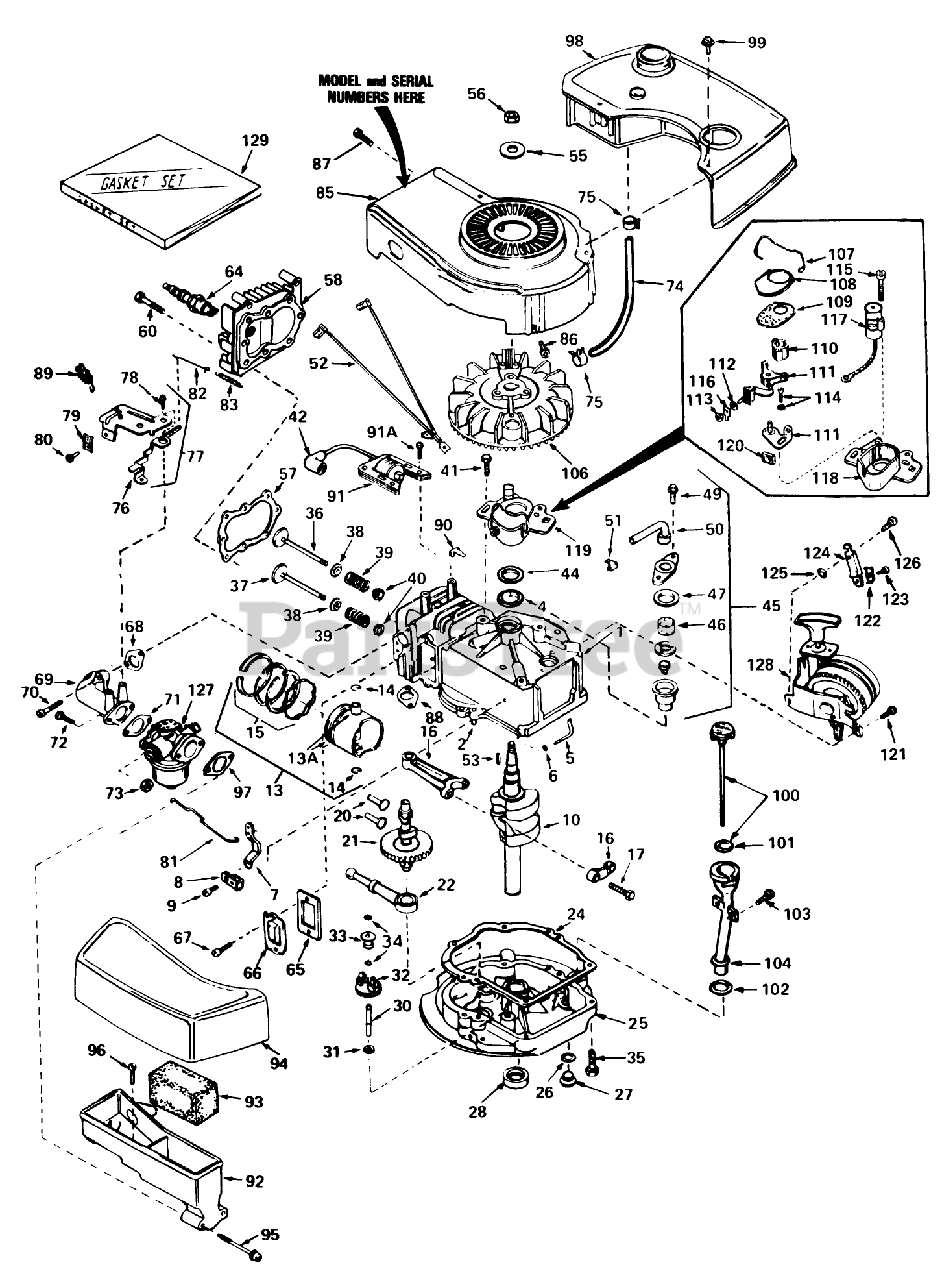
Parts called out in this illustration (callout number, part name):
1	Cyiinder Assy. (Incl. Ref. #2, 4 105)
2	Pin-Dowel
4	Seal-Oil
5	Rod, Governor (Incl. No. 36)
6	Washer-Flat
7	Governor Lever
8	Clamp-Lever, Governor
9	Screw
10	Crankshaft
13	Piston, Pin Ring Assy. (Std.)(Incl. Ref. #13A, 14 15)
13	Piston,Pin Ring Assy. (.010 over-size)(Incl. Ref. #13A, 14 15)
13	Piston, Pin Ring Assy. (Incl. Nos. 13A, 14 15)(.020 oversize)
13A	Piston Pin Assy. (Incl . Ref. . #14) (Std.)
13A	Piston Pin Assy. (Incl. Ref. #14) (.010 Oversize)
13A	Piston Pin Assy. (.020 oversize) (Incl. Ref. #14)
14	Ring-Retaining, Piston Pin
15	Ring Set Piston (Std.)
15	Ring Set Piston (.010 Oversize)
15	Ring Set Piston (.020 Oversize)
16	Rod Assy., Connecting (Incl. Ref. #17)
17	Bolt-Rod, Connecting
20	Lifter-Valve
21	Camshaft(Mech.Comp. Release)
22	Oil Pump ASM
24	Gasket, Mounting
25	Flange Assy., Mounting (Incl. Ref. #26thru 30)
26	Gasket-Oil Drain
27	Plug Oil Drain
28	Seal Oil
30	Shaft-Governor
31	Washer-Flat
32	Governor Gear ASM
33	Spool-Governor
34	Ring-Retaining
35	Screw (1/4-20 x 1-1/4)
36	Valve, Intake (Incl. Ref. #38, 39 40) (Std.)
36	Valve, Exhaust (1/32" Oversize) (Incl. Nos. 8, 9 10)
37	Valve, Exhaust (Standard) (Incl. Nos. 8, 9 10)
37	Valve, Exhaust (1/32" Oversize) (Incl. Nos. 8, 9 10)
38	Cap-Upper Valve Spring
39	Spring-Valve
40	Cap-Valve, Spring
41	Screw
42	Cover-Spark Plug
44	Gasket Stator
45	Breather Assy. (Incl. Ref. #46 thru 51)
46	Element-Breather
47	Gasket-Breather
49	Screw (10-24 x 9/16)
50	Tube, Breaker
51	Clip, Breather
52	Wire Ground
53	682488 LB GRASS HI-
55	Washer-Belleville
56	Nut-Flywheel
57	63573 GIL 42 SNWTHW
58	Head-Cylinder
60	Screw (5/16-18x1-1/2)
64	Plug, Spark (J17LM or equiv.)
64	Plug, Spark (Champion RCJ-8)
65	Gasket-Breather
66	Cover-Valve
67	Screw
68	Gasket-Intake
69	Pipe, Intake (Incl. No. 68)
70	Screw (1/4-20 x 1)
71	Gasket-Carburetor
73	Nut and Lock Washer (1/4-28)
74	Line-Fuel
75	Clamp-Line, Fuel
76	Lever Control
77	Control Assy., Speed (Incl. Nos, 76, 78 89)
78	Screw, Hex Washer Hd Shoulder Self-Tap
79	Conduit
80	Screw (10-32 x 3/8)
81	Link-Throttle
82	Link Governor Spring
83	Spring Governor
85	Housing Blower
86	Screw
87	Screw (10-24 x 9/16)
88	Gasket Exhaust
89	Terminal
90	Clip-Wire
91	Lamination Coil Assy. (Incl. No. 42)
91A	Screw
92	Body Air Cleaner
93	Filer, Air
94	Cove, Air Cleaner
95	Screw Fil Hd.
96	Screw, Hex Hd.
97	Gasket-Air Cleaner
98	Tank, Fuel
99	Screw (10-32 x 35/64)
100	Dipstick, Oil (Incl. Ref. #101)(Twist Lock)
101	O-Ring
102	Gasket
103	Screw (10-32 x 1/2)
104	Tube-Oil Fill
106	FIywheel
107	Spring Breaker Box
108	Cover-Dust
109	Gasket-Dust Cover
110	Cam-Breaker
111	Breaker Assy.
112	Washer
113	DECAL
114	Breaker Screw
115	Condenser Screw
116	Terminal, Ground
117	Condenser
118	Stator Plate
119	Stator Plate Assy. (incl. Nos. 107, 111 thru 118 120)
120	Felt,Cam Wiper
121	Screw (1/4-20 x 1/2)
122	Conduit
123	Screw (10-32 x 3/8)
124	Bracker
125	Washer
126	Screw (1/4-20 X 5/8)
127	Carburetor (Incl. Ref. #71 )
128	Starter
129	Gasket Set
